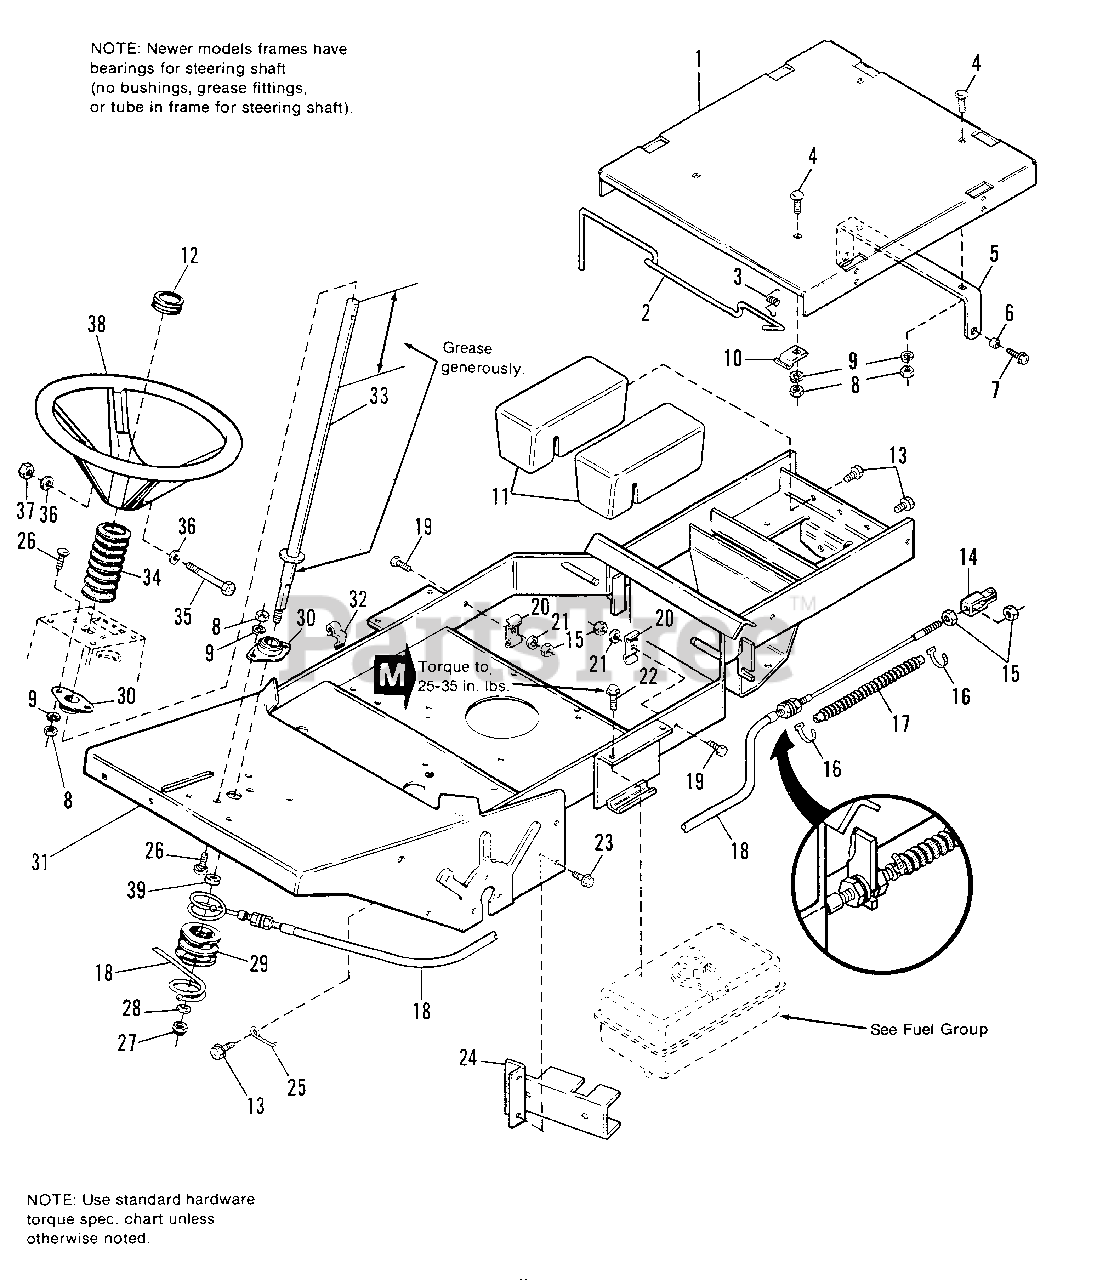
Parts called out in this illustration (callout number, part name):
2	ROD, Latch, Platform
3	SPRING, Torsion, Latch Rod
4	BOLT, Carriage, 5/16-18 x 3/4
5	BRACKET, Pivot, Platform
6	SPACER, Pivot Bracket
7	CAPSCREW, Taptite, 3/8-16 x 3/4
8	NUT, Hex, 5/16-18
9	LOCKWASHER, 5/16
10	CLIP, Latch Rod
11	WEIGHT, Rear
12	CAP, Steering Wheel
13	SCREW, Taptite, 5/16-18 x 3/4
14	CLEVIS, Steering Cable
15	NUT, Hex, 1/4-20
16	TIE, Steering Cable Boot, Self-locking
17	BOOT, Rubber, Steering Cable
18	CABLE, Steering
19	CAPSCREW, 1/4-20 x 1
20	CLAMP, Steering Cable
21	LOCKWASHER, 1/4
22	SCREW, Special, Fuel Tank
23	SCREW, Taptite, 5/16-18 x 1/2
24	SUPPORT ASSY., Fuel Tank
25	RETAINER, Steering Cable
26	CARRIAGE BOLT, 5/16-18 x 3/4
27	NUT, ESNA, Heavy Lock, 1/2-13
28	WASHER, 1/2
29	DRUM, Steering Shaft
30	BEARING, Flange
31	FRAME ASSY.
32	CLIP, Cable
33	STEERING SHAFT ASSY.
34	TUBE, Cover, Steering Shaft
35	CAPSCREW, 5/16-18 x 3-1/2
36	WASHER, 5/16
37	NUT, 5/16-18 Centerlock
38	STEERING WHEEL
